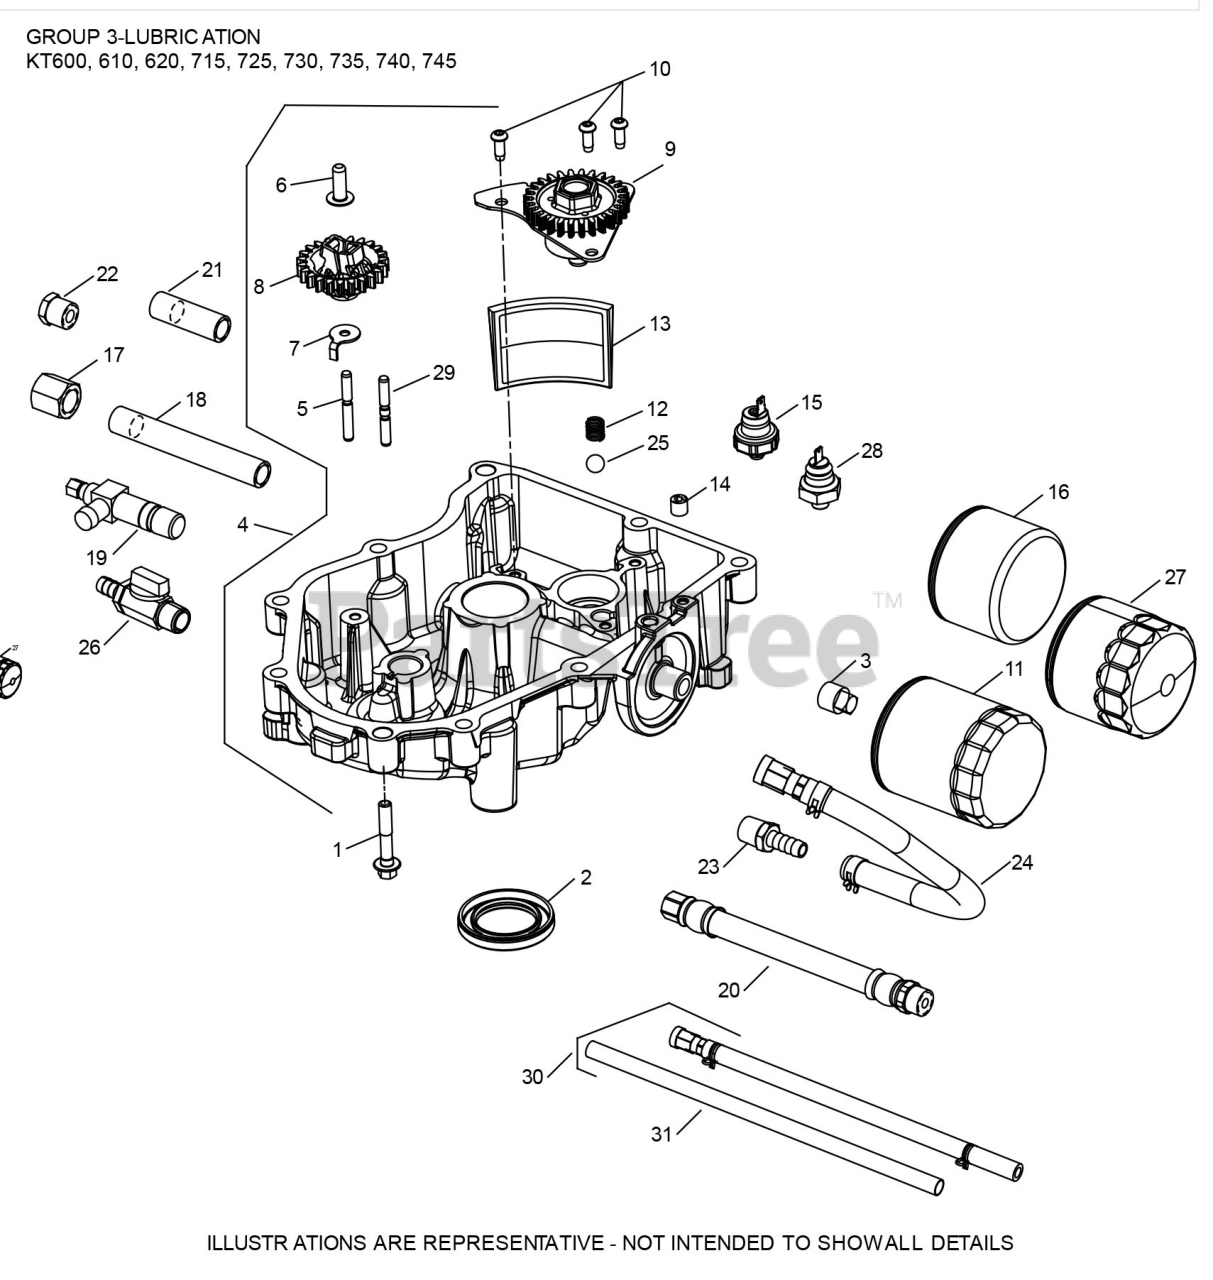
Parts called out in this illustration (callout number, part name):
6	PIN-GOV REGULATING
8	GEAR KIT-GOVERNOR
9	OIL PUMP ASSEMBLY
10	SCREW-BUTTON HEAD
11	OIL FILTER-LONG
12	COMPRESSION SPRING
25	PRESSURE RELIEF BA
28	OIL PRESSURE SWITCH
29	GOVERNOR GEAR SHAFT
